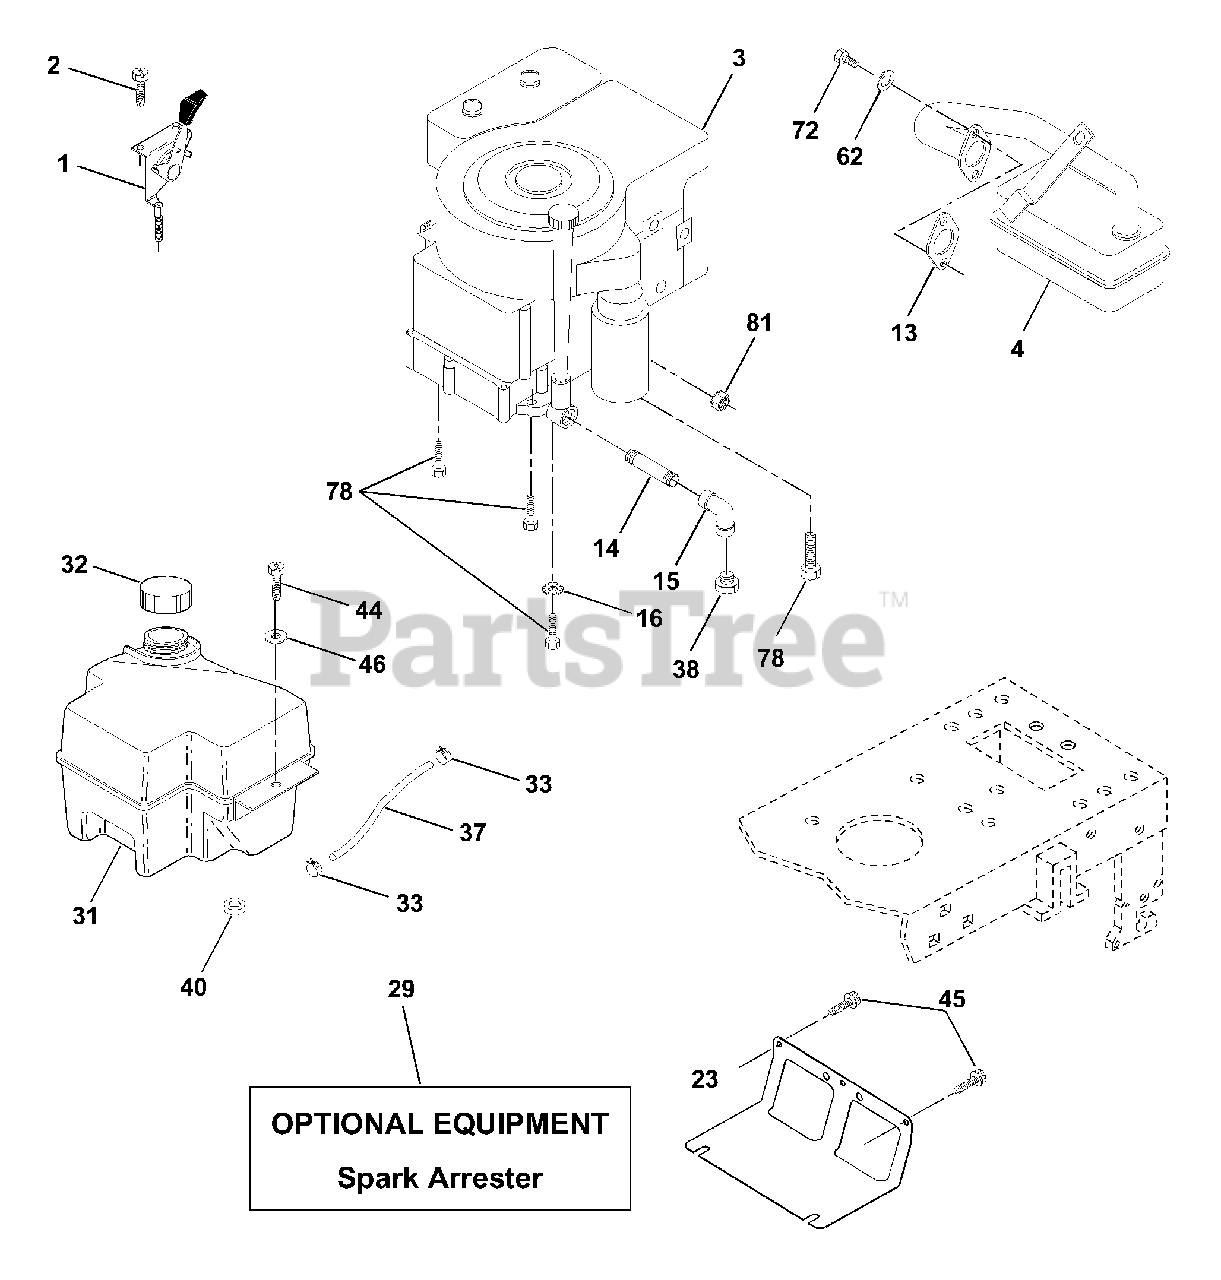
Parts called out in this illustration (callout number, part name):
1	Control Th/ch 23 5 LH Flag
2	Screw Hex Thd Cut 1/4-20x5/8 T
4	Muffler
13	Gasket Eng
14	Nipple Pipe
15	Elbow Std 90 Degree 3/8-18 Npt
16	Washer Lock Ext Tooth 3/8
23	Shield Brn/Dbr Guard
29	Kit Spark Arrestor (Flat Scrn)
31	Tank Fuel Front 2 00
32	Cap Asm Fuel W/sym Vented
33	Clamp Hose Black
37	Line Fuel 20"
38	Plug Oil Drain
40	Bushing Snap Nyl Blk Fuel Line
44	Screw Hexwsh Thdrol 1/4-20x3/4
45	Screw Hexwsh Thdr 3/8-16 x 3/4
46	Washer 9/32 X 7/8 X 16 Ga
62	Washer Lock Hvy Hlcl Spr 5/16
72	Screw Hex Hd Cap 5/16-18 x 3/4
78	Screw 3/8-16x1-1/4
81	Nut Keps 1/4-20 UNC
